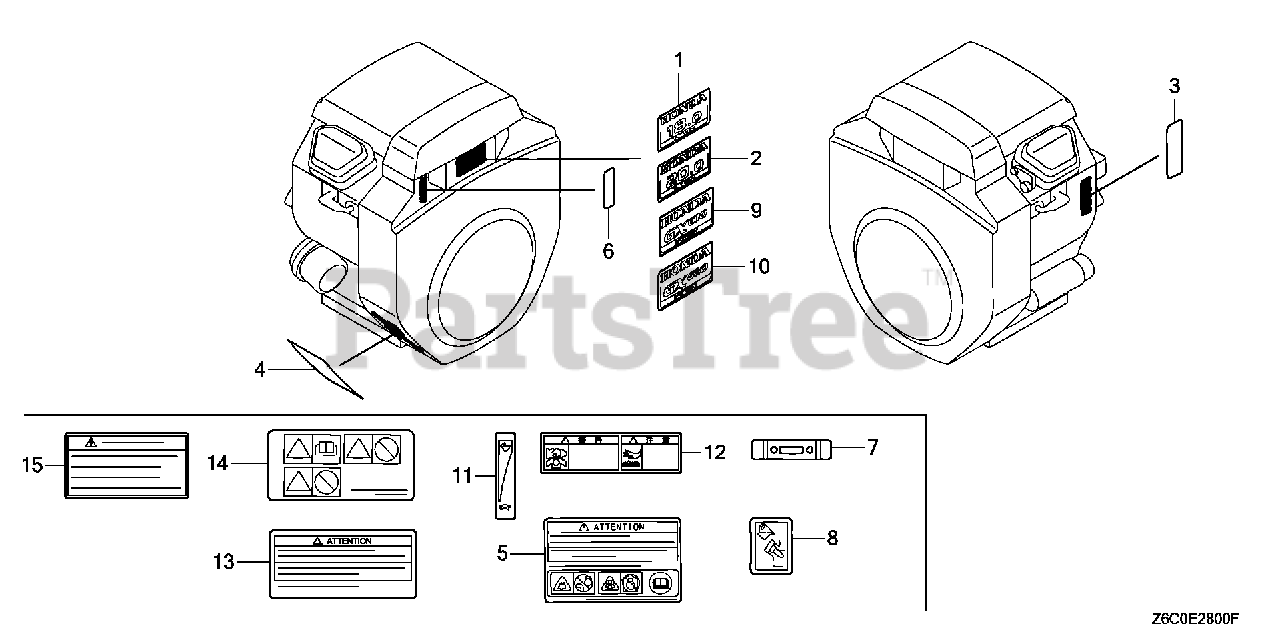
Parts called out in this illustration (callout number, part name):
4	MARK, OPERATOR CAUTION (ENGLISH)(MADE IN JAPAN)
10	MARK, EMBLEM (GX620)
13	MARK, OPERATOR CAUTION (FRENCH)(MADE IN JAPAN)
14	MARK, OPERATOR CAUTION (PICTOGRAPH)
